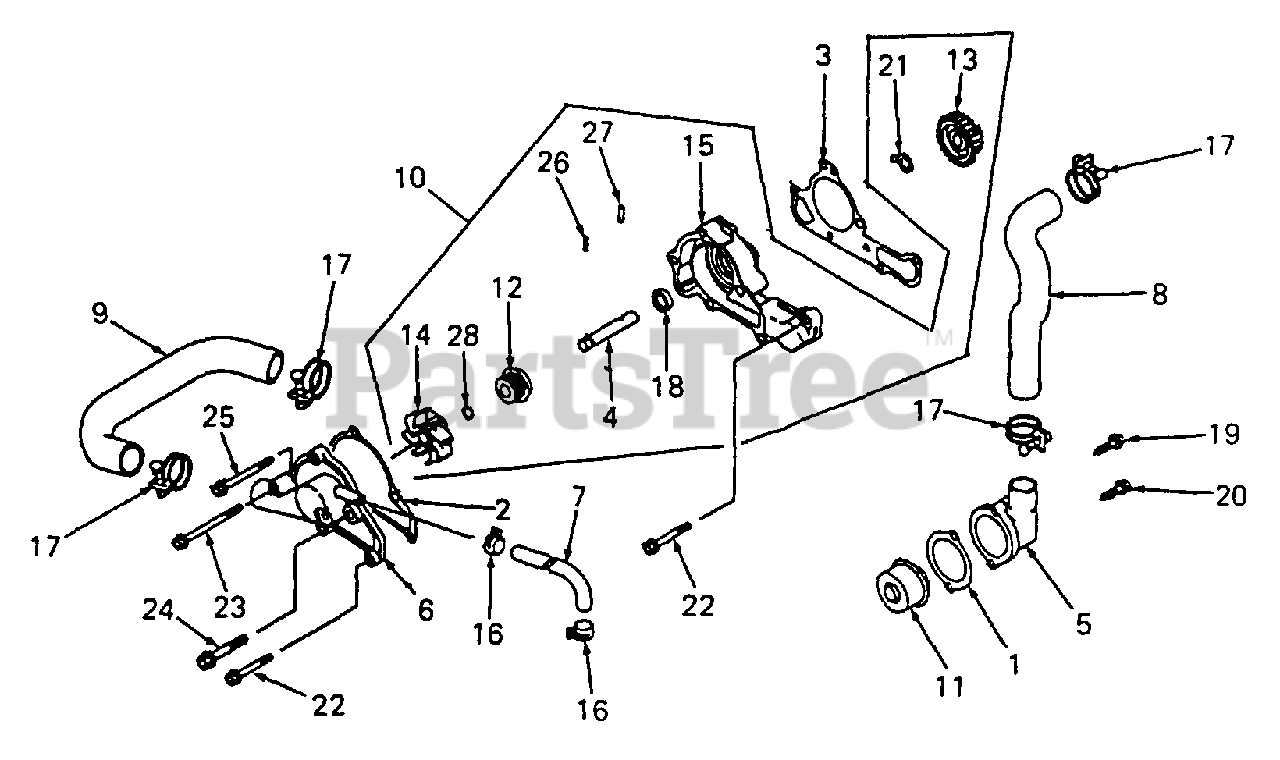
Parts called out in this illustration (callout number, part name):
1	Gasket, Thermostat Cover
2	Gasket, Pump Cover
3	Gasket, Pump Case
4	Shaft, Impeller
5	Cover, Thermostat
6	Cover, Pump
7	Hose, Cooling, 7.5 x 13.5 x 30.5
8	Hose, Cooling
9	Hose, Cooling
10	Pump Assy, Water
12	Seal, Mechanical
14	Impeller
22	Bolt, Flanged, 6 x 45
23	Bolt, Flanged, 6 x 75
24	Bolt, Flanged, 8 x 70
25	Bolt, 6 x 65
26	Pin, Dowel, 3 x 14
28	O-Ring, 7 MM
